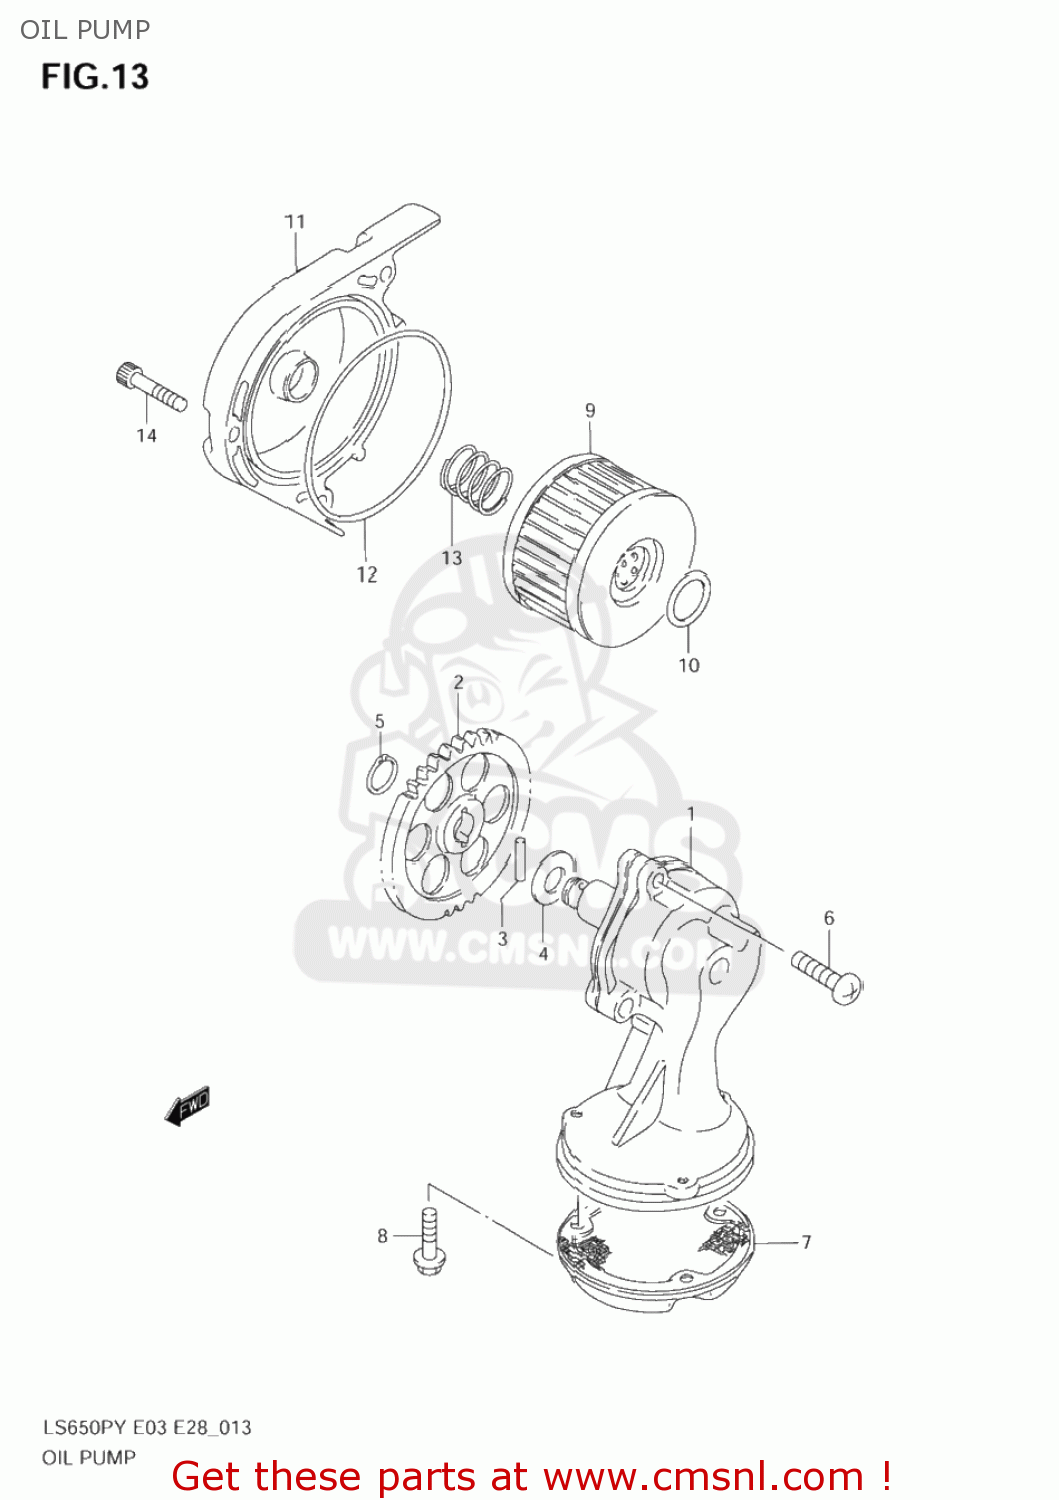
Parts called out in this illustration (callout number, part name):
1	PUMP ASSY,ENGINE OIL
2	GEAR,ENG OIL PUMP DRIVEN
3	PIN(4X15.8)
4	SHIM
5	CIRCLIP,10MM
6	SCREW
7	STRAINER,ENGINE OIL
8	BOLT
9	FILTER,ENGINE OIL
10	O RING(D:2.4,ID:15.8)
11	CAP,OIL FILTER
12	O RING(D:2.4,ID:73)
13	SPRING
14	BOLT
